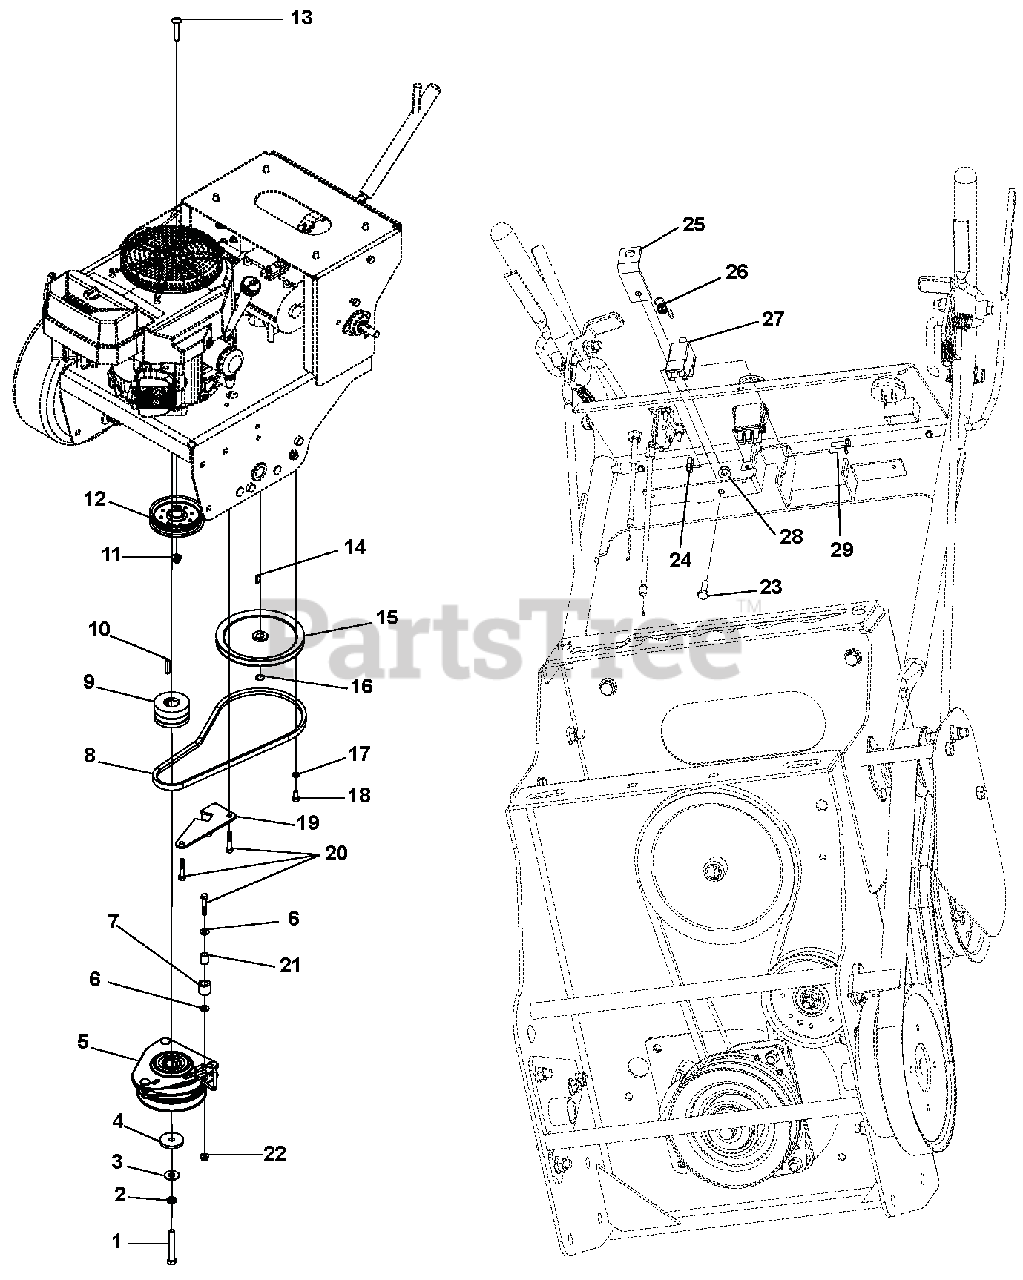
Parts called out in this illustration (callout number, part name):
1	BOLT, 7/16-20X3.00 HEX 5 Y
2	WASHER, .438 MED SPRG LOCK Y
3	@WSHR-FL-STL.50X1.25X.083 YWZC
4	WSHR-FL-STL .469X2.00X.25 YWZC
5	CLUTCH ASSY, OGURA# GT1A-HU02
6	@WSHR-FL-STL.312X.734X.065 YWZ
7	BUMPER,RUBBER .62X1.0X.88 LG
8	V-BELT, HA-RAW EDGE
9	SHEAVE,ENGINE 1.002IDX3.222PIN
10	KEY-SQ .248X1.25X.248
11	@NUT-LK-NYL-FLG .38-16 YWZC
12	PULLEY, V-BELT4.00X.379 W/BRG
13	BLT-RDHDSQNK .38-16X2.00 SHTYW
14	KEY-WDRF .19X.75 HRD #9
15	PLY-V 7.50 X .626
16	RG-RTNG-EXT .579X.035
17	WASHER, .313 MED SPRG LOCK Y
18	BOLT, 5/16-18X.750 HEX 5 Y
19	WMT, CLUTCH STOP
20	BOLT, 5/16-18X1.75 HEX 5 Y
21	BUSH.,S.407X.625X.813 ST
22	@NUT-LK-NYL-FLG .31-18 YWZC
23	BOLT, 1/4-20X.750 HEX 5 Y
24	LOCKNUT, 10-24 NYLOC Y
25	BRACKET, BRAKE LINK
26	SPRING-EXT .047X.438X1.45
27	SWITCH,INTERLOCK
28	@NUT-LK-NYL-FLG .25-20 YWZC
29	@SCR-MCH 10-24X.75 HWH YWZC
